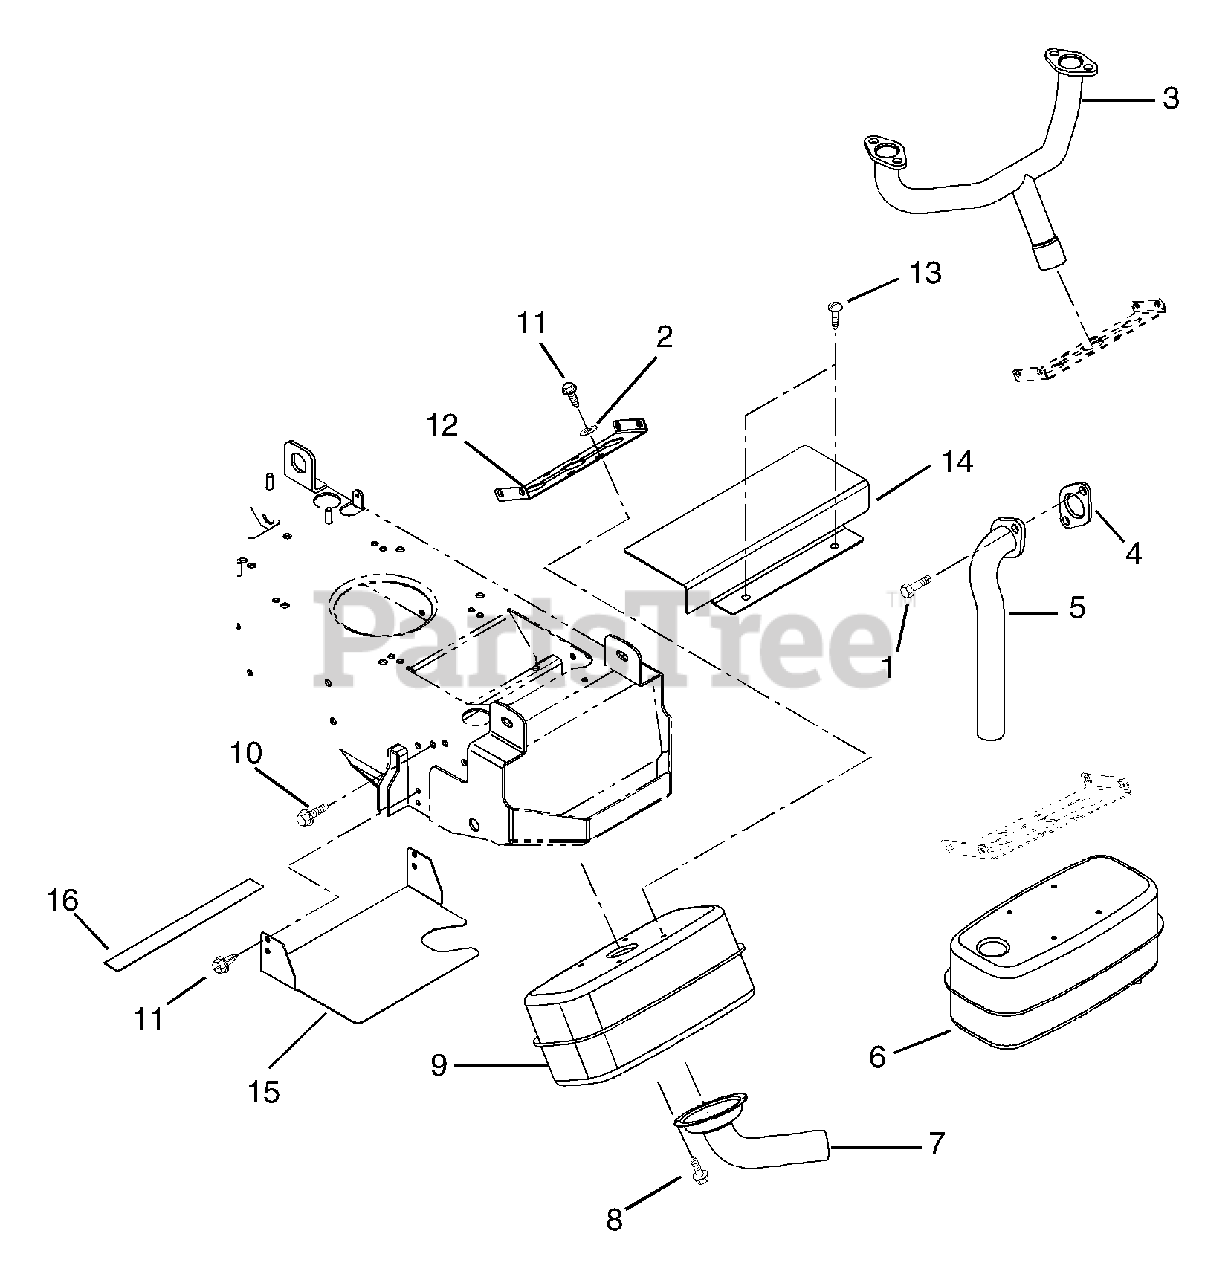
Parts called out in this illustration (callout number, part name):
1	SCR-CAP .31-18X.75 S/HD
2	@WSHR-FL-STL.250X.56X.049 YWZC
3	PIPE, EXHAUST INTEK V TWIN
4	GASKET B&S#272293
5	PIPE - EXHAUST
6	MUFFLER W/DEFLECTOR
7	DEFLECTOR - EXHAUST
8	SCR-TAP 8-32X.38 SL HWH YWZC
9	MUFFLER - EXHAUST
10	@SCR-TAP .31-18X.50 HWH TR YWZ
11	@SCR-TAP 12-24X.75 HWH YWZC
12	BRACKET - MUFFLER
13	@SCR-TAP .31-18X.50 HWH TR YWZ
14	SHIELD - HEAT
15	SHIELD, HEAT
16	HEAT SHIELD- FABRIC 1X10.75
